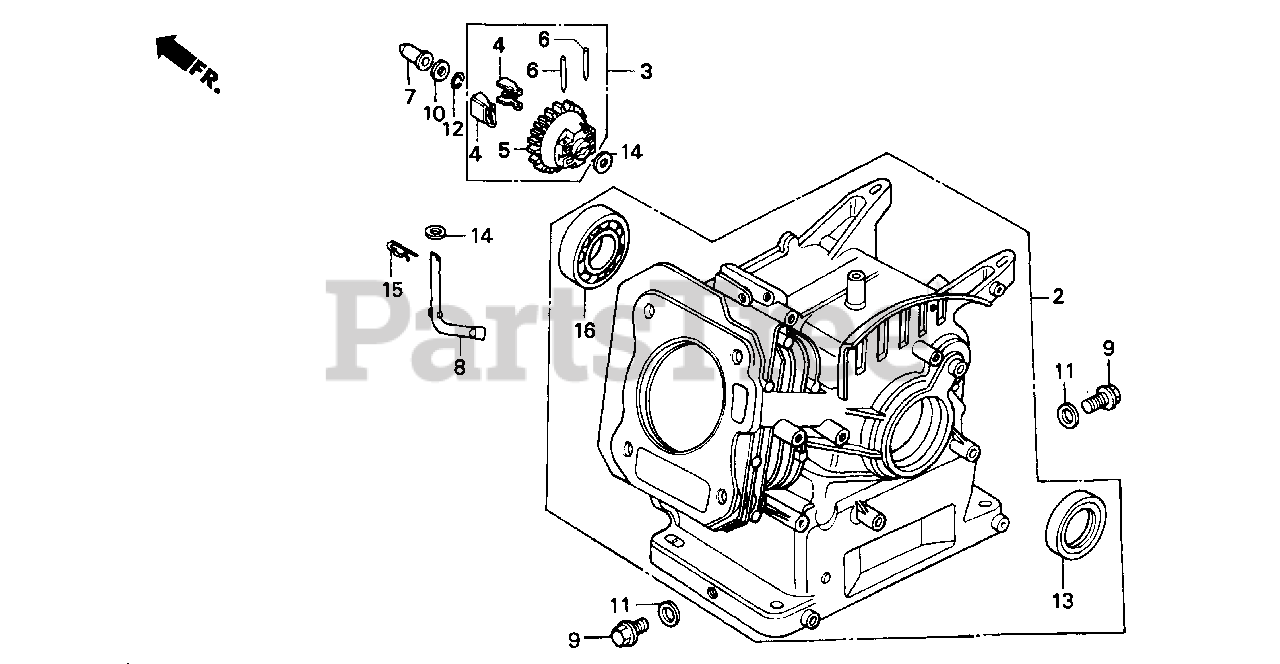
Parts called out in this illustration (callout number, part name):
2	CYLINDER ASSY. (010)
2	CYLINDER ASSY.
3	GOVERNOR ASSY.
4	WEIGHT, GOVERNOR
5	HOLDER, GOVERNOR WEIGHT
6	PIN, GOVERNOR WEIGHT
7	SLIDER, GOVERNOR
8	SHAFT, GOVERNOR ARM
9	BOLT, DRAIN PLUG
10	WASHER, THRUST (6MM)
11	WASHER, DRAIN PLUG (10.2MM)
12	CLIP, GOVERNOR HOLDER
13	OIL SEAL (25X41X6)
14	WASHER, PLAIN (6MM)
15	PIN, LOCK (8MM)
16	BEARING, RADIAL BALL (6205)
